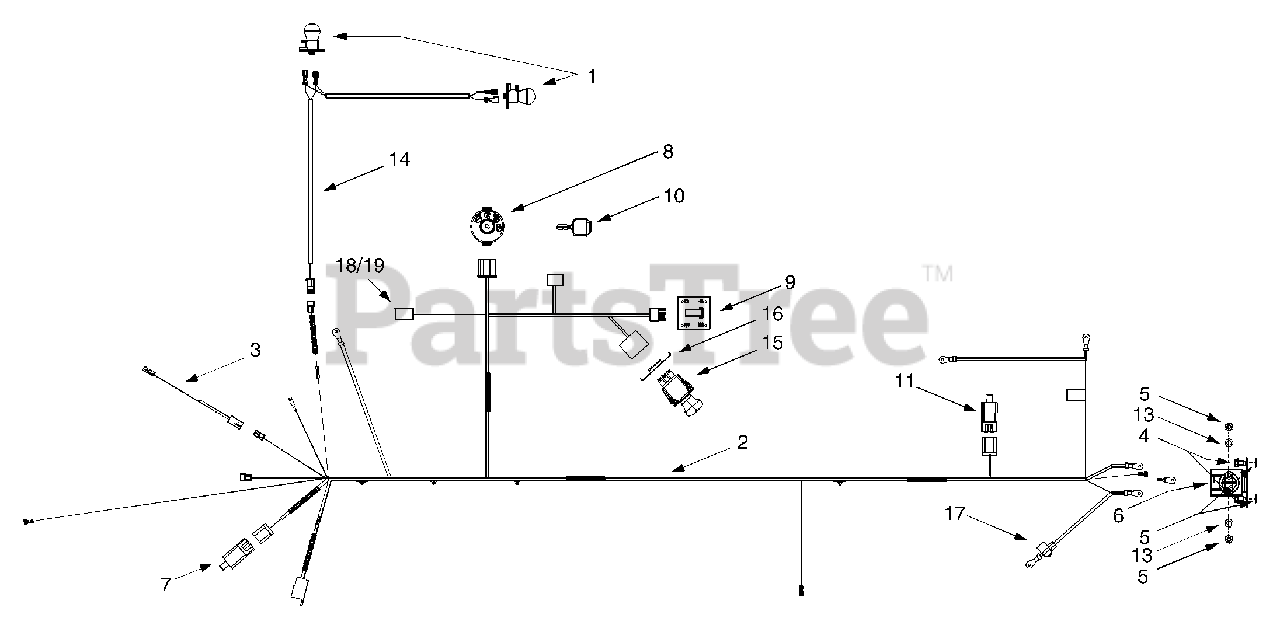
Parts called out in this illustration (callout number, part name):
1	Bulb/Socket Headlight Assembly
2	Wiring Harness w/o Ref. 14
3	Harness Adapter, #18 x 5
4	Self Tapping Screw, 1/4-20 x .5
5	Hex Nut, 1/4-20
6	Solenoid, 12-volt, 100 Amp
7	Snap Mount Safety Interlock Switch (Brake)
8	Ignition Switch
9	Indicator Monitor / Hour Meter
10	Ignition Key
11	Safety Plunger Switch (Seat)
13	Lock Washer, 1/4
14	Headlight Harness
15	Electric PTO Switch
16	Retainer Bracket
17	Positive Terminal Cover (Boot)
19	20-amp Fuse
